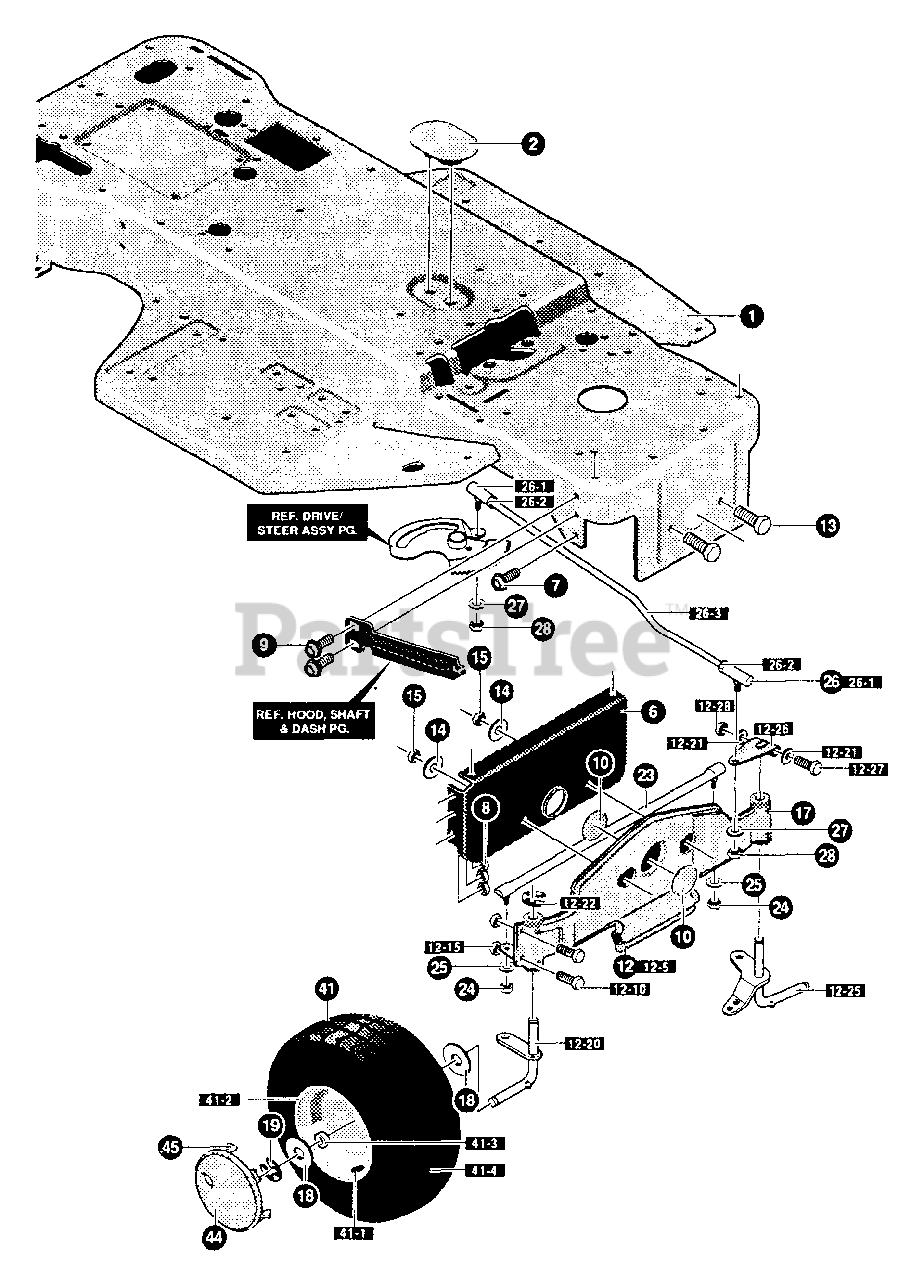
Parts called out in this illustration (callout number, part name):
1	FRAME EURO
2	COVER, SECTOR BOLT PLAS GREY
6	BRACKET, FRONT AXLE SUPPORT
7	SCREW, 5/16-18 X .75WDFLLK
8	NUT, 5,16-18 HXWDFLLK
9	SCREW 5/16-18 X .75 HXWDFL
10	PLUG, FRONT AXLE 1.938DIA X .062"
12	SUB-ASSY FR AX ERO LT SHORT
12-5	AXLE, ASSY FRONT WELD BLK
12-10	SCREW, 5/16-18 X .75 HHC
12-15	NUT, 5/16-18 REGHEXCTRLK
12-20	ASSY SPDLE RH EROLT
12-21	WASHER, FLAT .391 X 1.00 X .125
12-22	RING, RETEX .57 X .05TRU5133-75
12-25	ASSY SPDLE LH EROLT
12-26	ARM STEERING UPPER BLACK
12-27	SCREW, 3/8-16 X 2.50 HHC
12-28	NUT, 3/8-16 REGHXCTRLK
13	SCREW, 3/8-16X3.00 HHC
14	WASHER, .39IDX1.25DX.07 BELLVIL
15	NUT, 3/8-16 REGHXCTRLK
17	ZERK, GREASE FITTING
18	WASHER, FLAT .755X1.31X .075
19	RING, RETEX .57X.05TRU5133-75
23	TIE ROD .625DIA GRND ENGAGER
24	NUT, 3/8-24 REGHEX
25	WASHER, REGSPTLK .393X.68X.10
26	LINK ASSY .625DIA DRAG LT 4WS
26-1	BALL JOINT 3/8 THD SHORT STUD
26-2	NUT, 3/8-24 REGHEXJAM
26-3	LINK, .625DIA DRAG LT 4WS
27	WASHER, REGSPTLK .393X.68X.10
28	NUT, 3/8-24 REGHEXJAM
41	TIRE & RIM, PU 15X6.0X6 WHI
41-1	VALVE STEM
41-2	RIM, WHEEL
41-3	BEARING, FL
41-4	TIRE 15X6.0X6
44	HUB CAP, 6" EURO GREY
45	CLIP HUB CAP TINN #C25467-017-4
